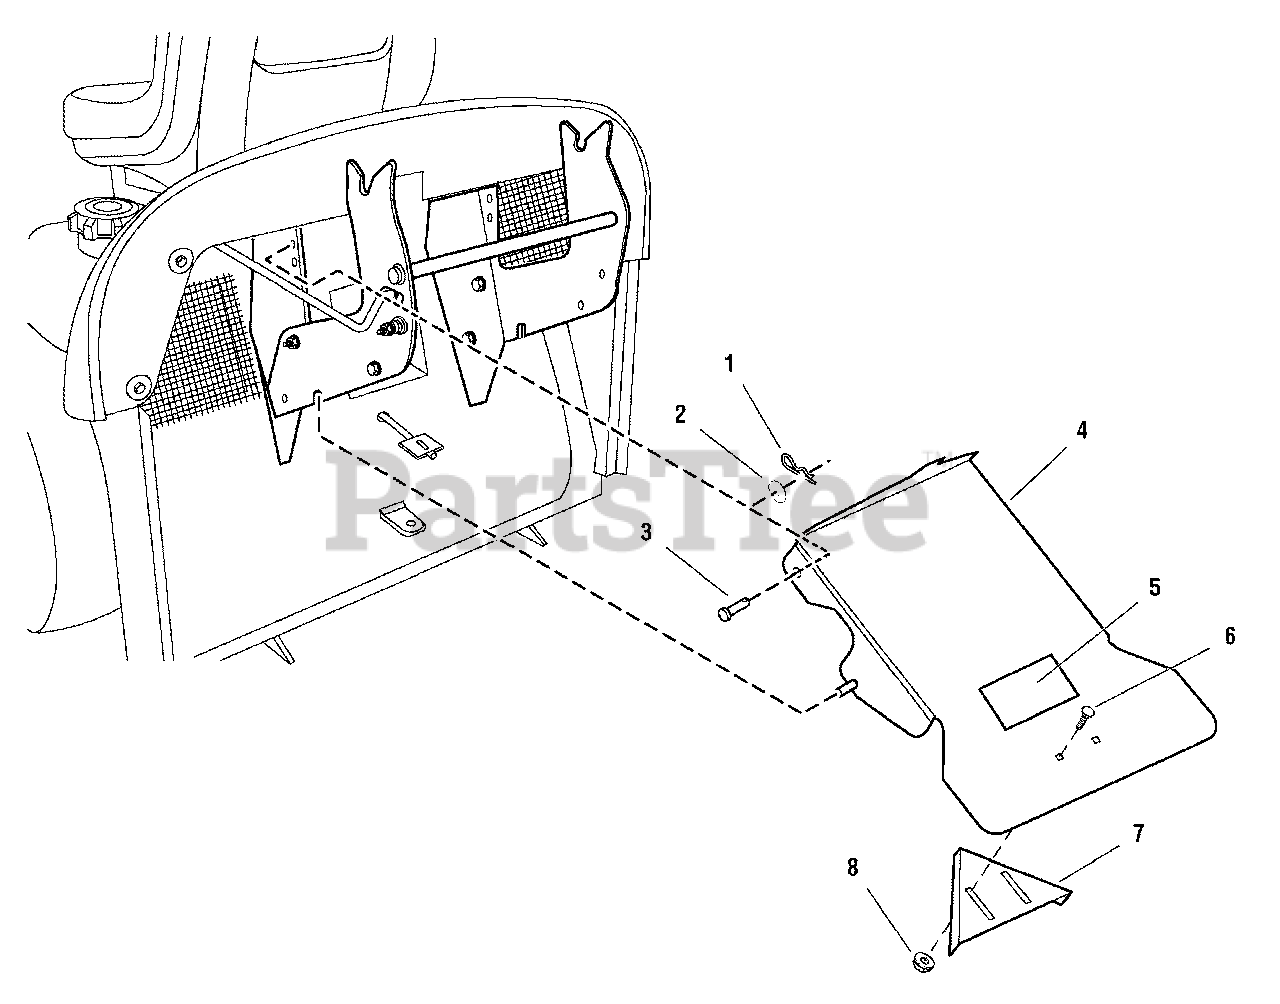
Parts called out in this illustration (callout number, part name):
1	CLIP, Hair Pin
2	WASHER, 5/16
3	PIN, Clevis
4	DEFLECTOR & PINS ASSEMBLY
5	DECAL, Danger Operating without Catcher
6	BOLT, Carriage, 1/4-20 x 5/8
7	DEFLECTOR, 16GA
8	NUT, Hex KEPS Conical Washer, 1/4-20
